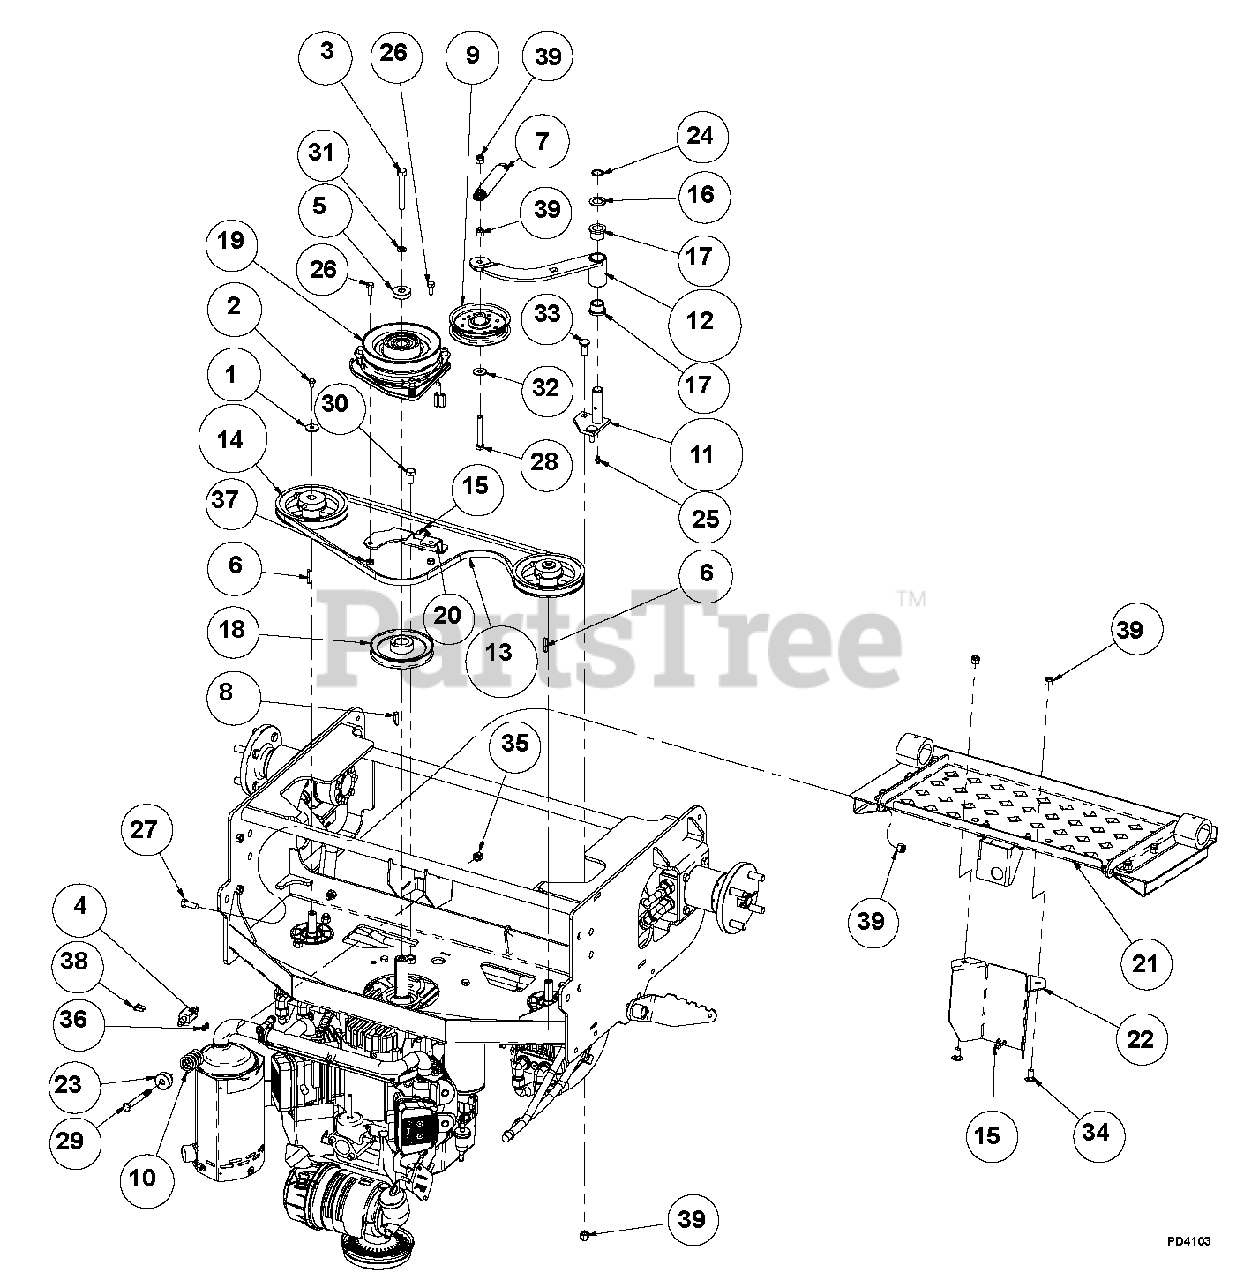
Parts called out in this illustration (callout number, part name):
1	Washer, .250 Wide Heavy Flat Y
2	Bolt, M6 x 1.00 x 10 Hex 8.8 Y
3	Bolt, Hex .44-20 x 3.00 Grade 5
4	Switch (N.0.)
5	Spacer, .468 x 1.38 x .375 Y
6	Key, M5 x M5 x M30 RD
7	Spring, External .900 x .135 x 4.50 Y
8	Key, .250 x .250 x .995 TPR
9	Pulley, V-Belt 4.00 x .379 w/Bearing
10	Spring, COM 1.22 x .162 x 2.50 Y
11	Weldment, Pivot Idler Mount
12	Weldment, Idler Arm
13	Belt, Pump Drive
14	Assembly, Pump Pulley w/Set Screw
15	Cable Tie, .15 x 8.50
16	Bushing, MACH .750 x 1.25 x .048 Y
17	Bearing, FLG .750 x 1.00 x .750 BRNZ
18	Pulley, V-Belt 4.78PD x 1.000 W/KEY
19	Clutch Assy, Ogura
20	Plate, Clutch Dog
21	Assembly, Foot Plate (See Foot Plate on page 22.)
22	Cover, OPC
23	Washer, Spring Y
24	Snap Ring, .750 x .042 External
25	Fitting, 1/4-28 STRGT Grease Zerk
26	Bolt, 5/16-18 x .750 Hex 5 Y
27	Bolt, 3/8-16 x 1.00 Hex 5 Y
28	Bolt, 3/8-16 x 2.50 Hex 5 Y
29	Bolt, 3/8-16 x 3.25 Hex 5 Y
30	Bolt, 7/16-14 x .750 Hex 5 Y
31	Washer, .438 Medium Spring Lock Y
32	Washer, .375 Regular Flat Y
33	Bolt, 3/8-16 x 1.00 Carriage Grade 5 Y
34	Bolt,3/8-16x3/4 Car Grade 5 LN Y
35	Nut, 3/8-16 Standard Hex Grade 5 Y
36	Locknut, 10-24 Nyloc Y
37	Locknut, 5/16-18 Nyloc Y
38	Screw, 10-24 x .625 PAN PHL MACY
39	Locknut, 3/8-16 Nyloc Y
